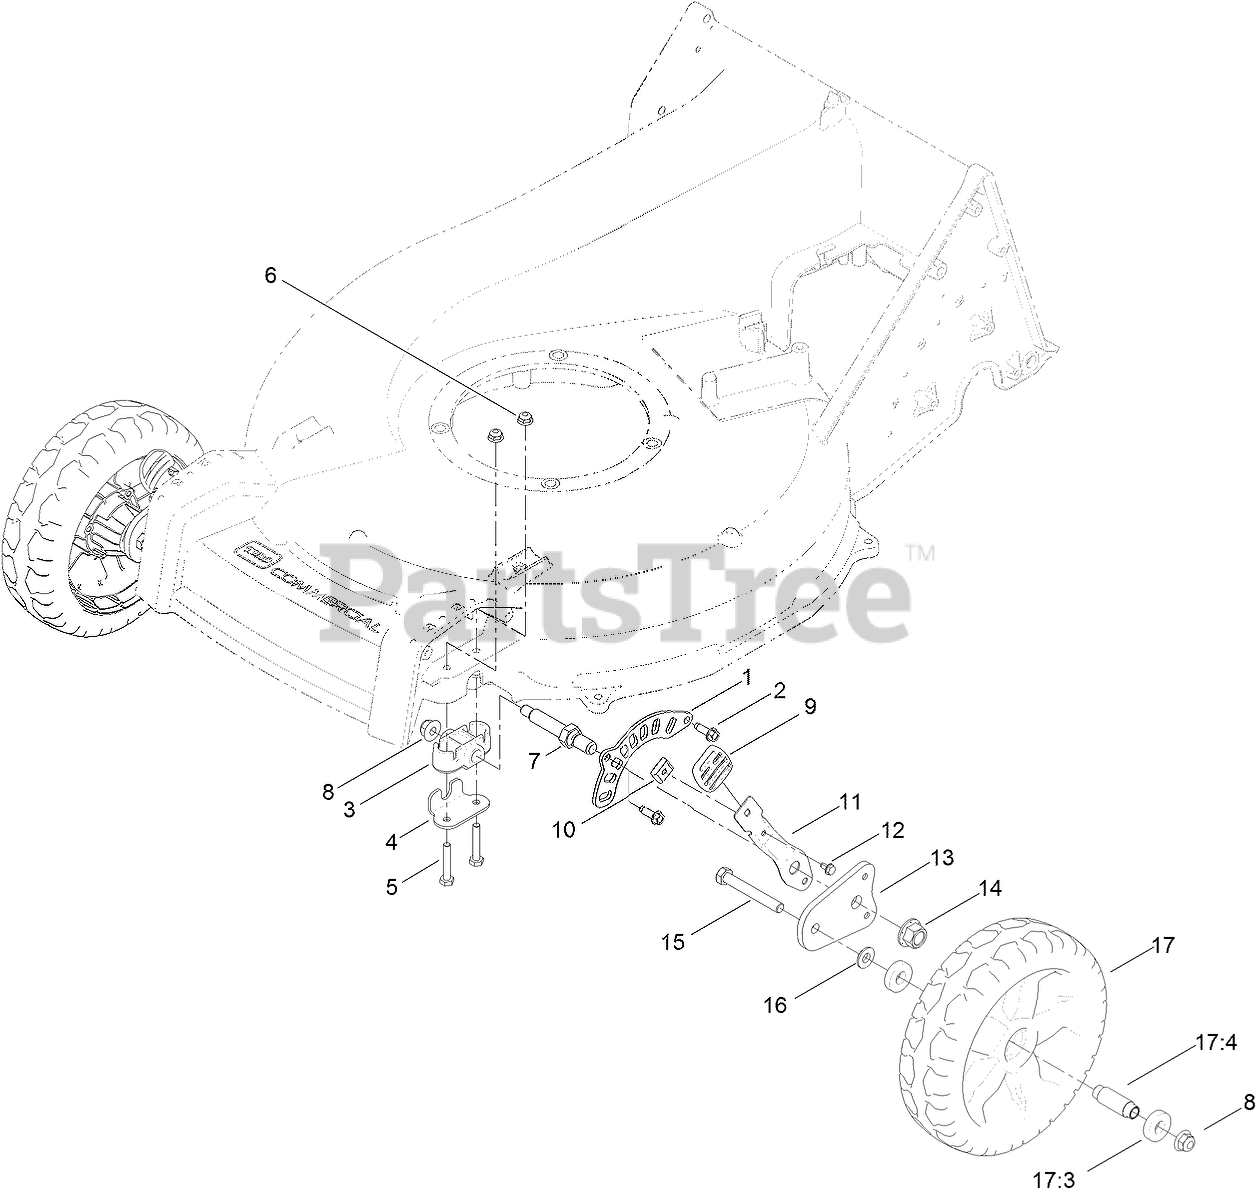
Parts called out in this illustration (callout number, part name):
1	PLATE-HOC, FRONT
2	SCREW-HWHTF
3	BUSHING-AXLE, FRONT HOC
4	RETAINER-BUSHING, FRONT AXLE
5	SCREW-HH
6	NUT-HF
7	AXLE-WHEEL
8	NUT-HF, NI
9	KNOB-LEVER, HOC
10	KEY-ARM, SPRING
11	ARM-SPRING
12	SCREW-HWH
13	ARM-PIVOT, FRONT
14	NUT-LOCK
15	SCREW-HH
16	SPACER-COVER, WHEEL
17	WHEEL
17:3	BEARING-WHEEL
17:4	SPACER
